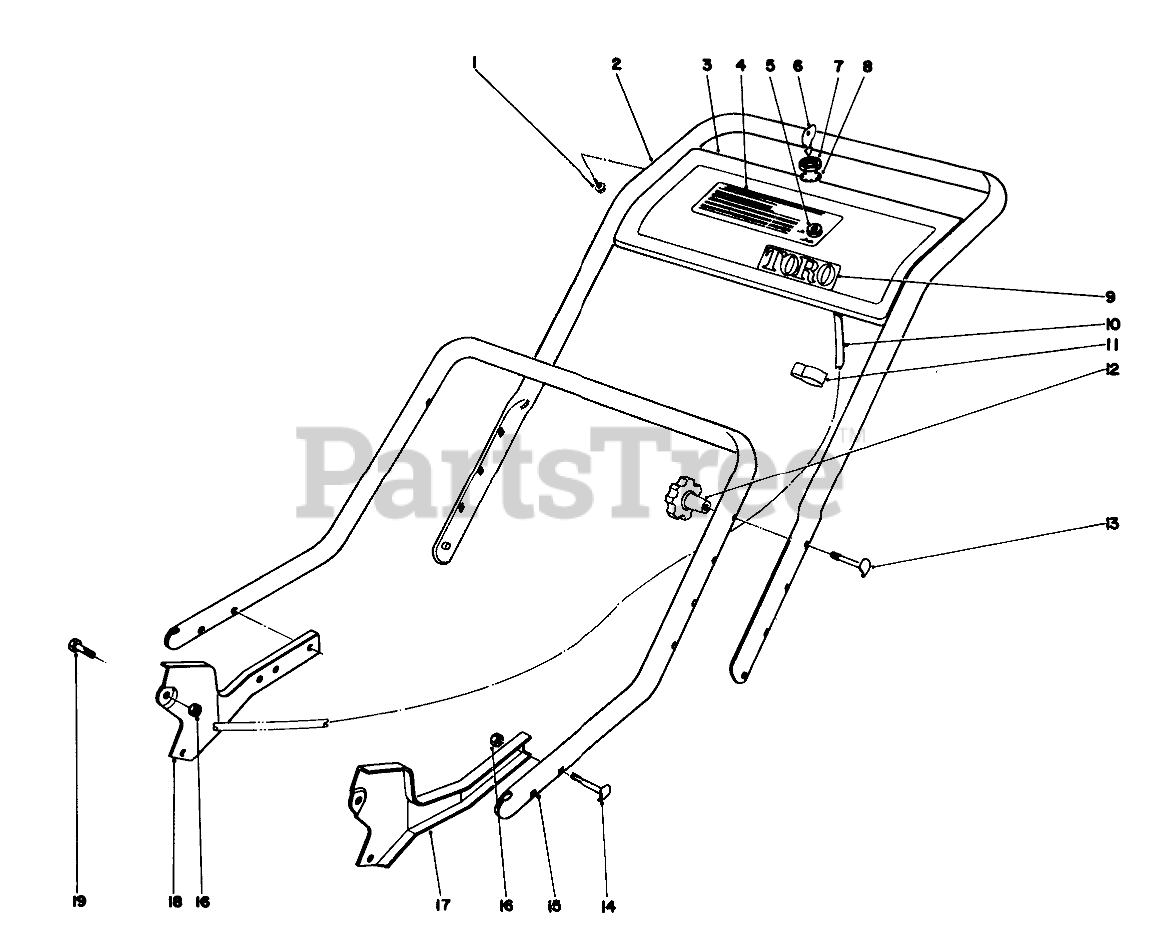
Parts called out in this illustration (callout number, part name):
1	SCREW-HWHTF
2	Upper Handle
3	Control Plate
4	Decal-Control Plate
5	Switch
6	Key
7	NUT-HH
8	WASHER-TOOTH, INTERNAL
9	TORO LOGO DECAL
10	Wire Harness
11	BOWDEN CLIP
13	HANDLE SCREW
14	Handle Screw
15	Lower Handle
16	Nut
17	Latch Handle L.H.
18	RH HANDLE LATCH
19	SCREW-HH
